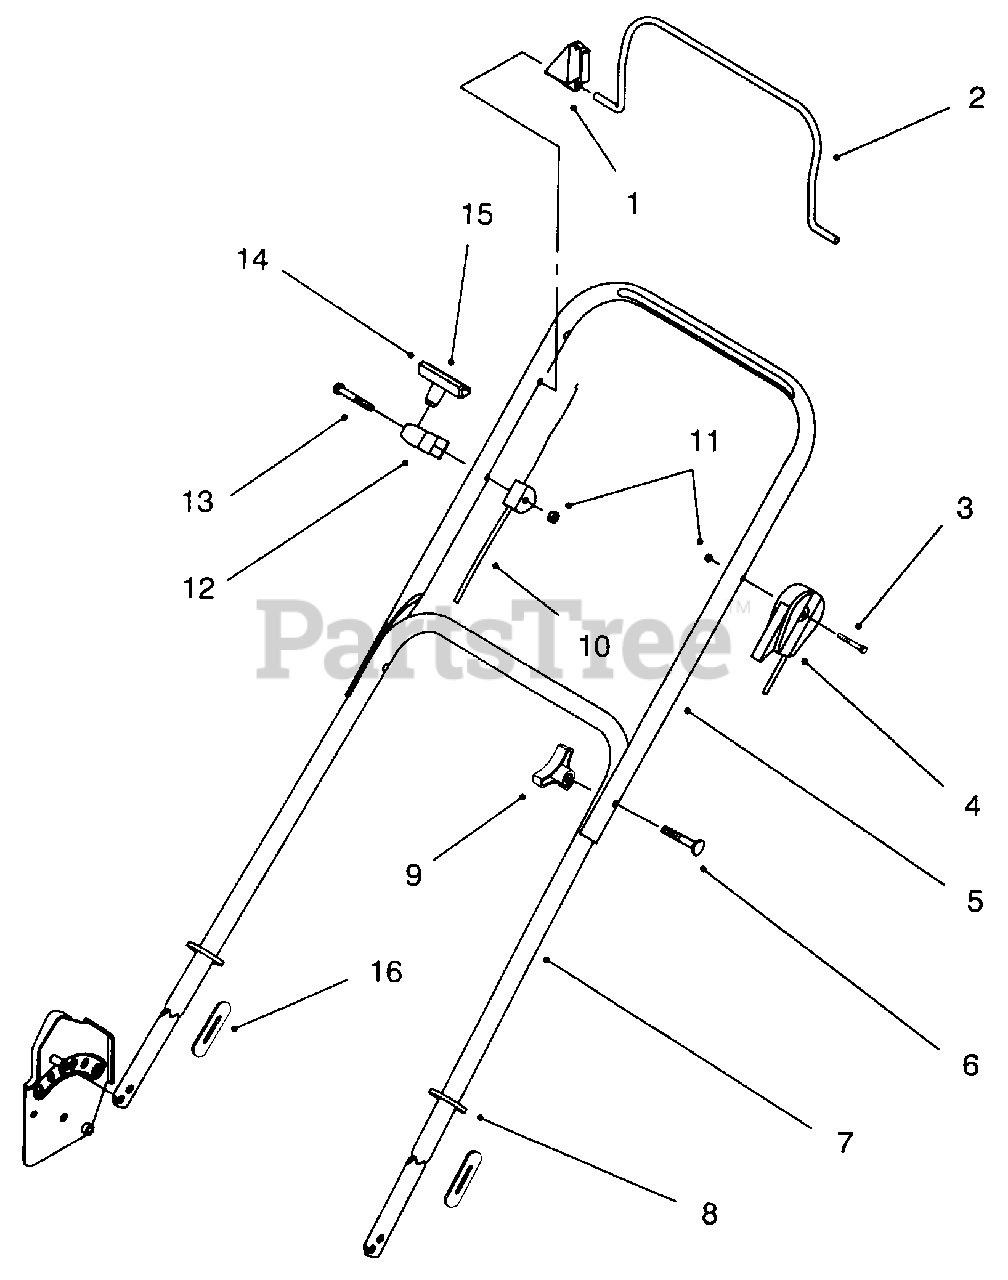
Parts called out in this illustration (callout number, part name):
1	Stop-Pivot
2	Bail-Flywheel Brake
3	Screw-Hex Hd. Cap
4	Cable-Throttle
5	Handle-Upper
6	Screw-Handle
7	Handle-Lower
8	Tie-Cable
9	Knob
10	Cable-Flywheel Brake
11	Nut-Lock
12	Guide-Rope
13	Screw-Hex Hd Cap
14	Handle-Starter
15	Clip-Rope Insert
16	Guard-Handle
